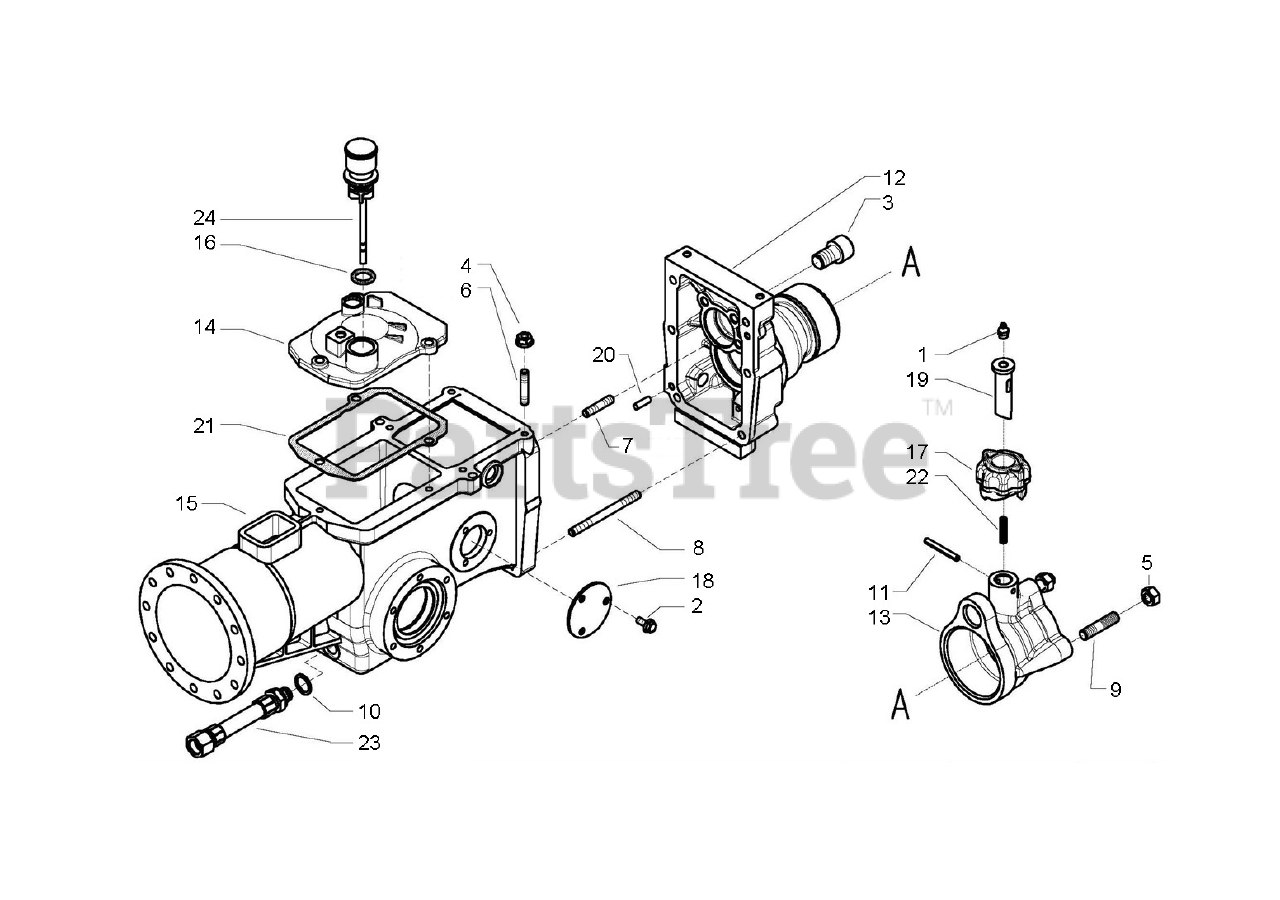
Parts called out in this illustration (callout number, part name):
1	LUBRICATOR M10
2	SCREW
3	SCREW TCEI M16X25 UNI 5931
4	SELFLOCK NUT M8 6S DIN 6927
5	SELFLOCK NUT M12X1,25
6	STUD BOLT M8X38X14X20
7	STUD BOLT M8X58X16X16
8	STUD BOLT M8X68X14X36
9	STUD BOLT
10	COPPER WASHER 16,7X22/1,5
11	ROLL PIN
12	REAR COVER, 750
13	BUSHING COMPLETE
14	GEARBOX HOUSING COVER
15	BOX CASING
16	RUBBER RING
17	COVER
18	COVER
20	CYLINDRICAL PLUG
21	COVER GASKET
22	SPRING
23	HOSE
24	DIPSTICK
